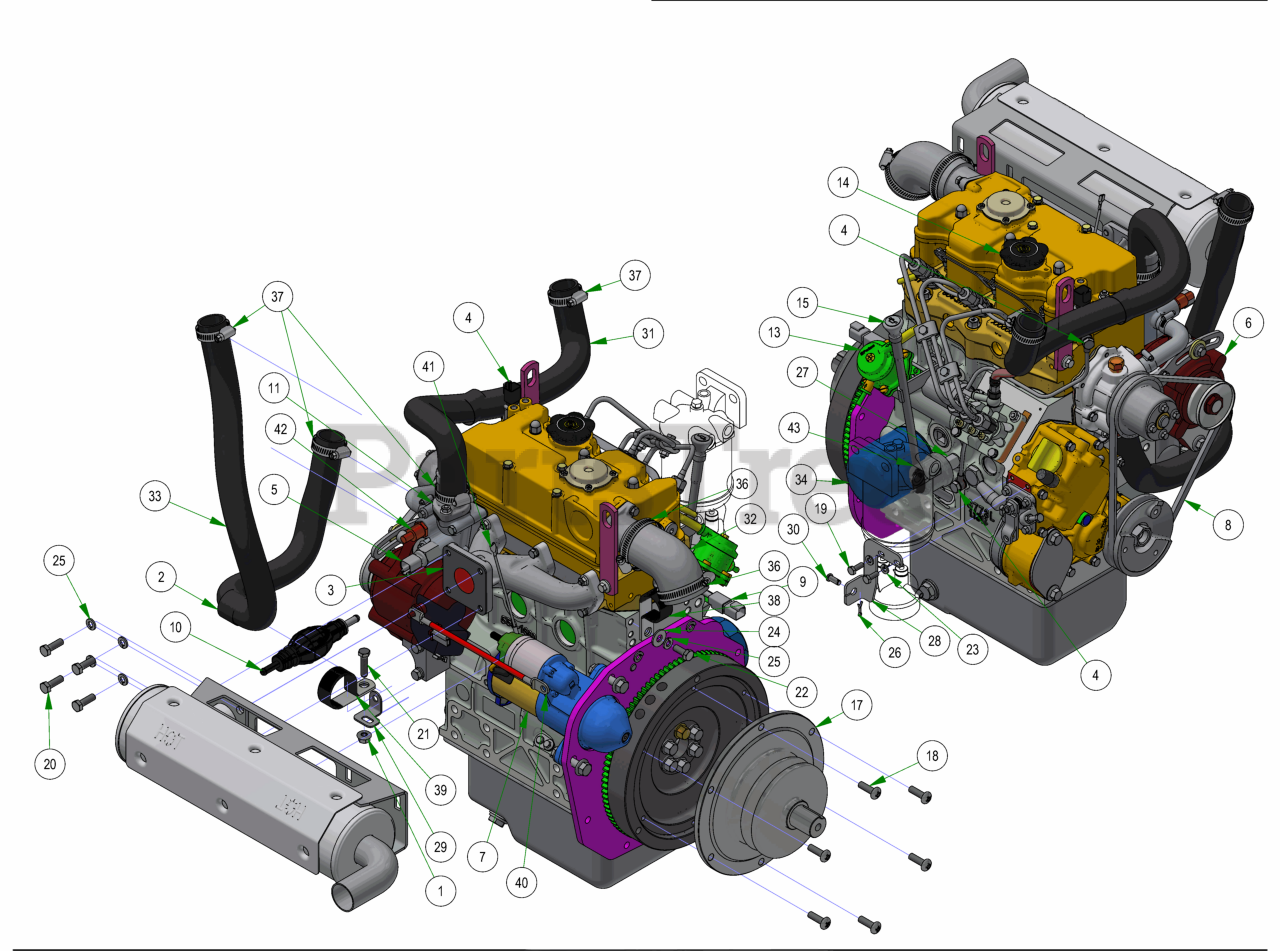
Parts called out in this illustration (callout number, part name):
1	5/16-18 NYLON INSERT FLANGE LOCKNUT ZINC
2	2019 Plastic Mesh Hose Loom
3	Diesel Muffler Gasket
4	OIL PRESSURE SWITCH
5	COOLANT TEMPERATURE SWITCH
6	ALTERNATOR
8	ALTERNATOR BELT
9	FUEL SHUTOFF SOLENOID
10	FUEL PRIMING BULB PUMP
11	THERMOSTAT GASKET
12	FUEL PRE-FILTER
13	FUEL LIFT PUMP
14	OIL FILLER CAP
15	OIL LEVEL DIPSTICK
16	Fuel Separator Bowl
17	2019 Diesel Stub Shaft Double V
18	5/16-18 X 1 BUTTON TORX CAP SCREW ZINC
19	M6-1.0 X 16MM DIN 933 HEX TAP BOLT (CL 8.8) ZINC
20	M8-1.25 X 25MM DIN 933 HEX TAP BOLT (CL 10.9) ZINC
21	5/16-18 X 1-1/4 HEX C/S (GR.5) ZC
22	M8-1.25 X 20MM DIN 933 HEX TAP BOLT (CL 8.8) ZINC
24	5/16 USS FLAT WASHER (7/8 OD) ZINC
25	5/16 SPLIT LOCKWASHER ZINC
26	3/32 X 1/2 COTTER PIN ZINC
27	8mm x 1/8 mpt Adaptor
28	Throttle Bracket
29	Diesel Radiator Hose Clamp Bracket
30	1/4 X 5/8 CLEVIS PIN PLAIN
31	2019 Diesel Radiator Hose Upper
32	2019 Diesel Air intake Hose
33	2019 Diesel Radiator Hose Lower
34	OIL FILTER
35	Fuel Filter
36	2-1/2" Hose Clamp
37	1 1/8" Hose Clamp
38	Diesel Hydraulic Hose Clamp
39	Diesel Clamp 1 3/4" Vinyl
40	Red Battery Cable Alternator to Starter Cable
41	2022 DIESEL JUMPER WIRE, WHITE, 14AWG
42	Coolant Temperature Sender
43	Oil Pressure Guage with Sender
